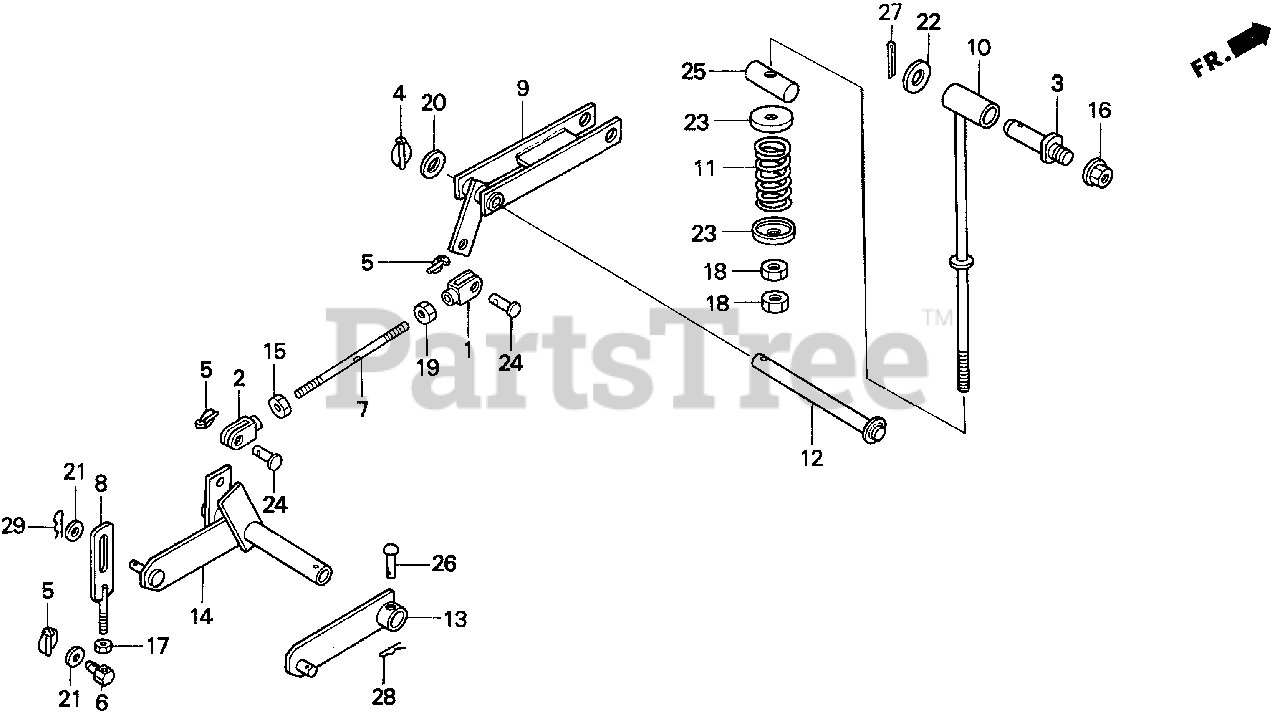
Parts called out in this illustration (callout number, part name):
1	ROD, R. ADJUSTING LIFT
2	ROD, L. ADJUSTING LIFT
3	PIN, LIFT ARM
4	LINCHPIN ASSY. (1/4)
5	LINCHPIN ASSY.
6	PIN, FR. LINK ADJUSTING
7	ROD, CUTTER DECK LIFT
8	PLATE, CUTTER DECK LIFT
9	LINK, CUTTER DECK LIFT
10	ROD, LIFT LINK
11	SPRING, LIFT DAMPER
12	SHAFT, LIFT LINK
13	ARM, R. LIFT
14	ARM, L. LIFT
15	NUT, HEX. (0.625 NF PLATED)
16	NUT (5/8 NC HEX. LOCK)
17	NUT (1/2 NC JAM)
18	NUT (5/8 NC HEX.)
19	NUT, HEX. (0.625 NF RH PLATED)
20	WASHER, SAE FLAT (7/8)
21	WASHER, STD SAE (5/8)
22	WASHER (3/4X1-3/16X10GA)
23	WASHER (16MM)
24	PIN, FR. LINK
25	PIN, DAMPER SPRING (NOT AVAILABLE)
26	PIN, LIFT ARM
27	PIN, SPLIT (3/32X1-1/2)
28	PIN, SAFETY (3/32)
29	PIN, LOCK (16MM)
